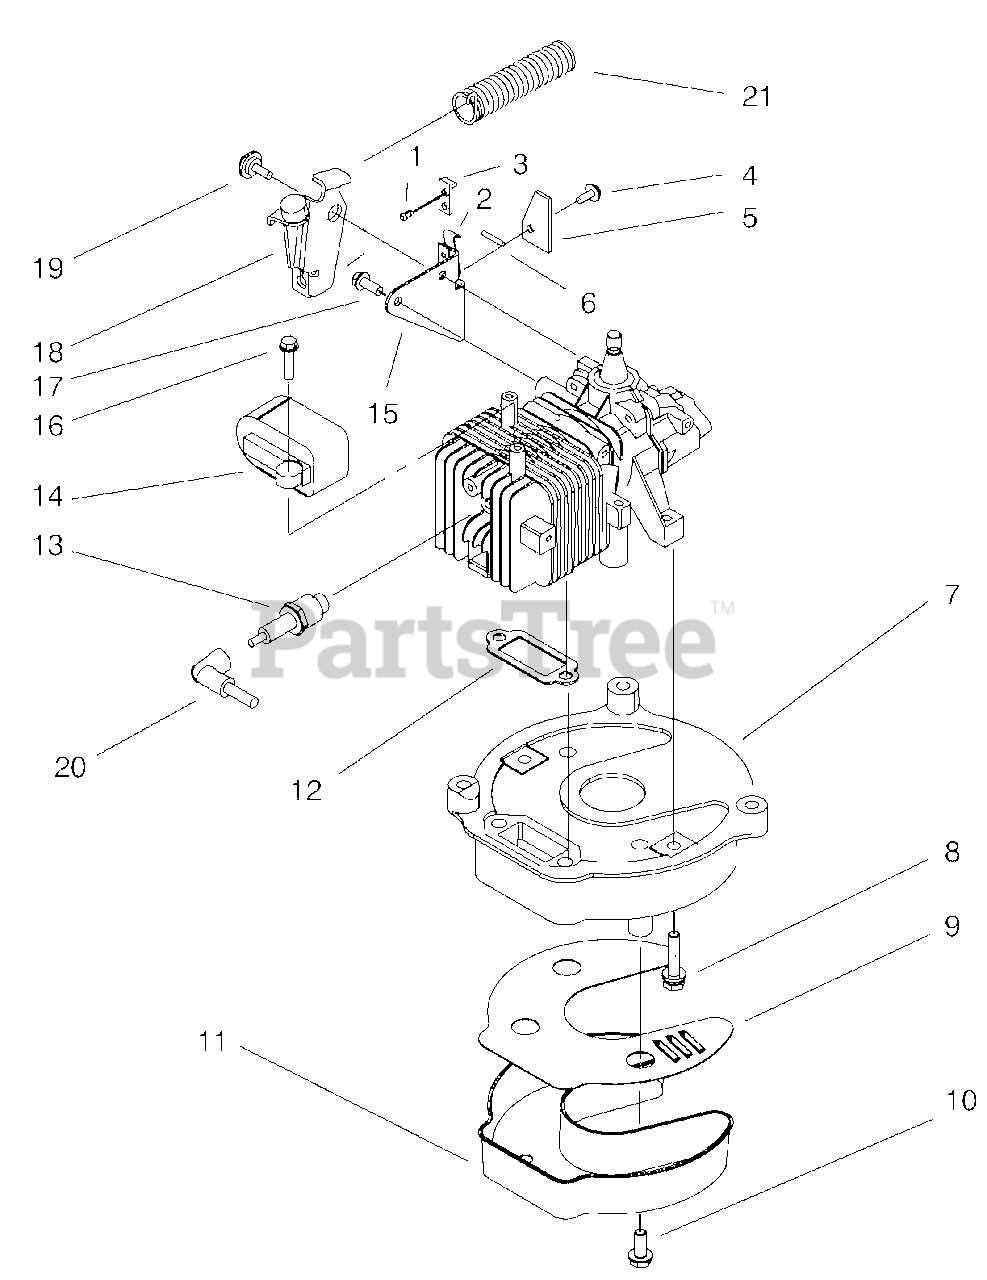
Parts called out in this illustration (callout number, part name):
2	Strap-Ground
3	Strap-Insulation
4	Screw-Thread Forming
5	Stop-Ground Strap
6	Wire-Brake Switch Lead
7	Plate-Muffler
11	Cover-Muffler
12	Gasket-Exhaust
13	Plug-Spark
14	Ignition Assembly (Incl. Ref. #20)
15	Plate-Brake Mount
16	Screw-Hex Washer Hd.
17	Screw
18	Plate-Brake Assembly
19	Screw-Shoulder
20	Lead & Cover Assembly
21	Spring-Compression
